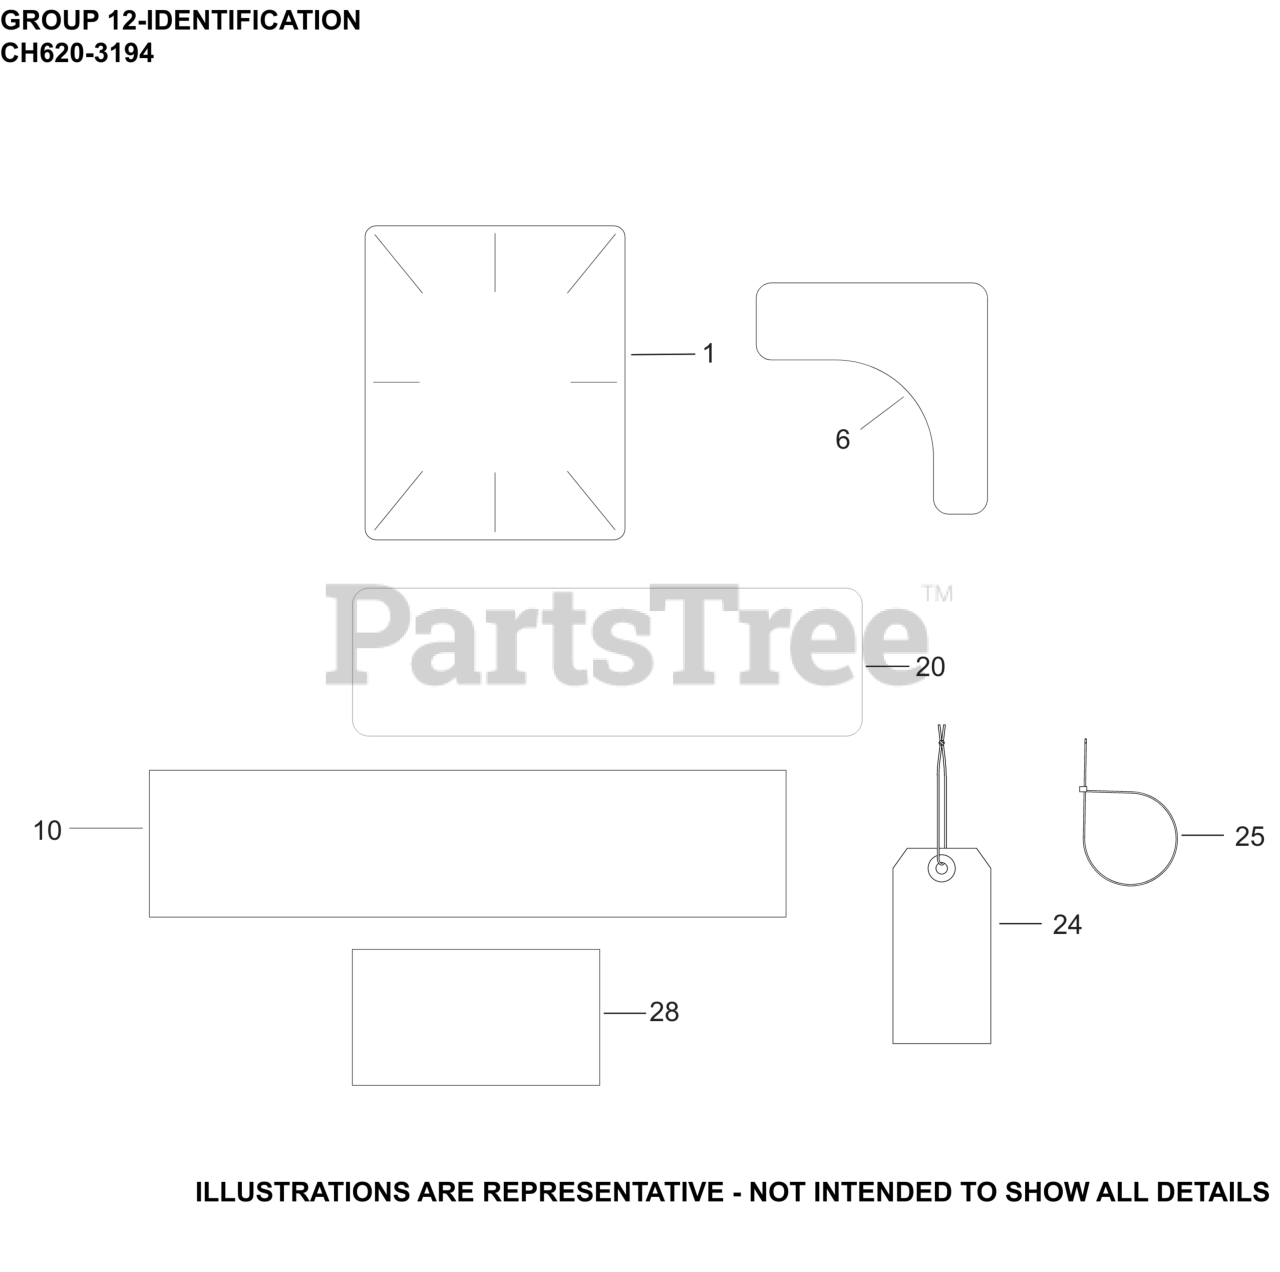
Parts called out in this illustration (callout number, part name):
1	LABEL, CLEAR LAMINATION
6	DECAL, KEY SWITCH
10	DECAL, STOPPING INSTRUCTION
20	DECAL LPAC, 674cc/CV-CH620
24	TAG, HANG (OIL SENTRY)
28	DECAL, USA
